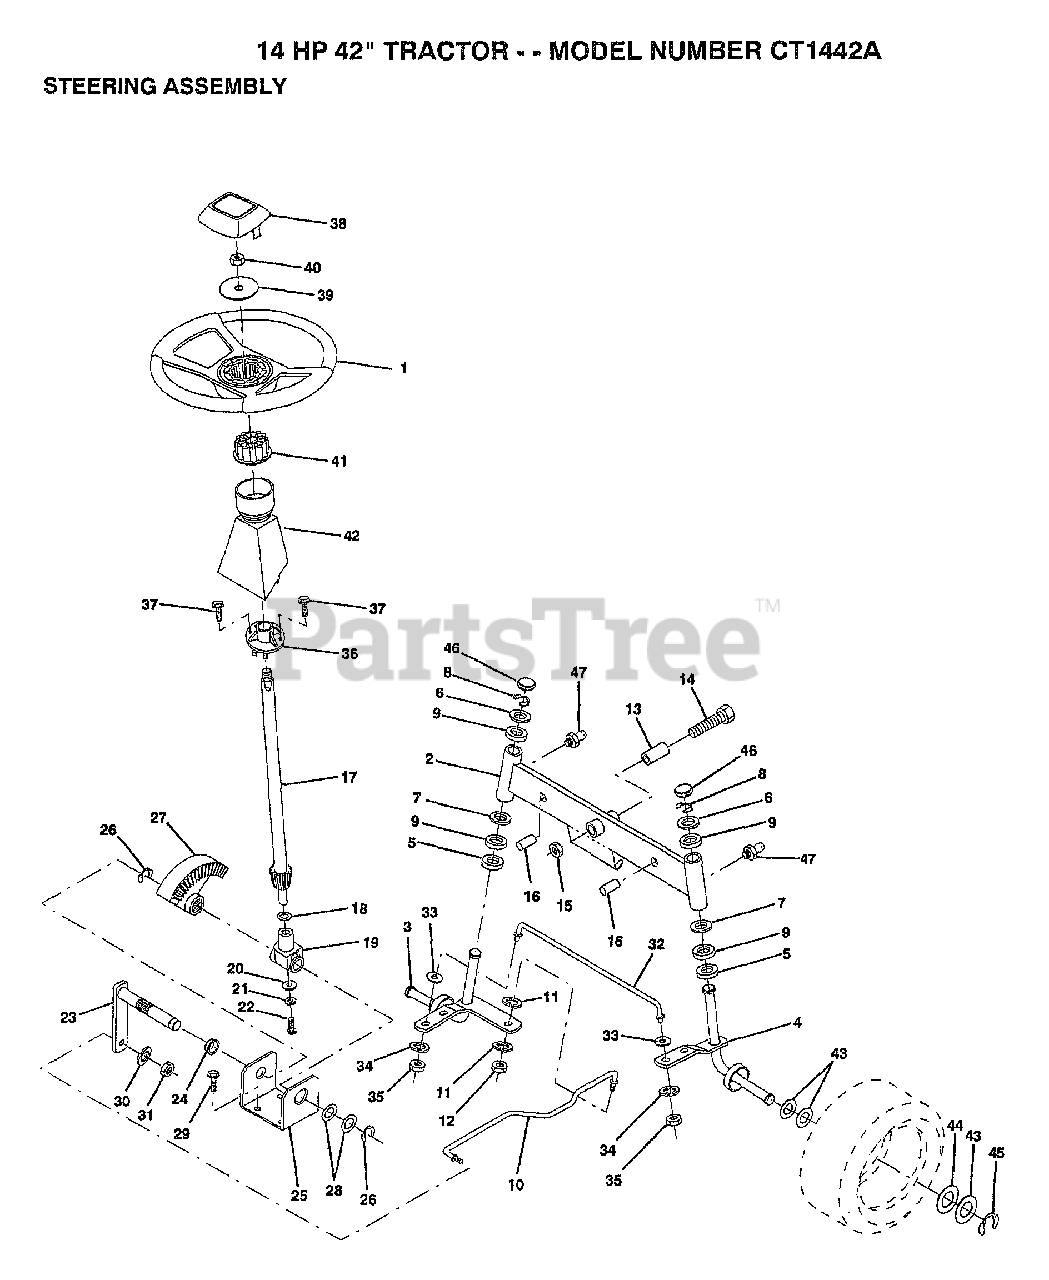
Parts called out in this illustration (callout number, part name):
3	SPINDLE LH
4	SPINDLE RH
5	WASHER .T
6	WASHER
7	WASHER
8	RING
9	COL. SRTG. BEAR.
11	LOCKWASHER
13	BEARING
14	BOLT HEX 5/8-11
15	"NUT-LOC,FLANGE LT"
16	AXLE PIN
17	SHAFT ASM
18	THRUST WASHER
19	SUPPORT.SHAFT
21	LOCKWASHER
22	"SCREW,SPECIAL"
24	NYLINER T
25	"BRKT,STEERING"
26	RING
27	GEAR SECTOR
28	WASHER .T
29	SCREW
30	LOCKWASHER
32	TIE ROD
33	WASHER M
34	LOCKWASHER
35	NUT.LOCK.5/16-24
38	ST WHL INSERT CAP
39	WASHER T
40	GRIPCO NUT
41	ADAPTER-WHEEL LT
42	"TUBE, STR SHAFT"
43	WASHER
44	WASHER
45	RING
46	CAP
47	ZERK M
